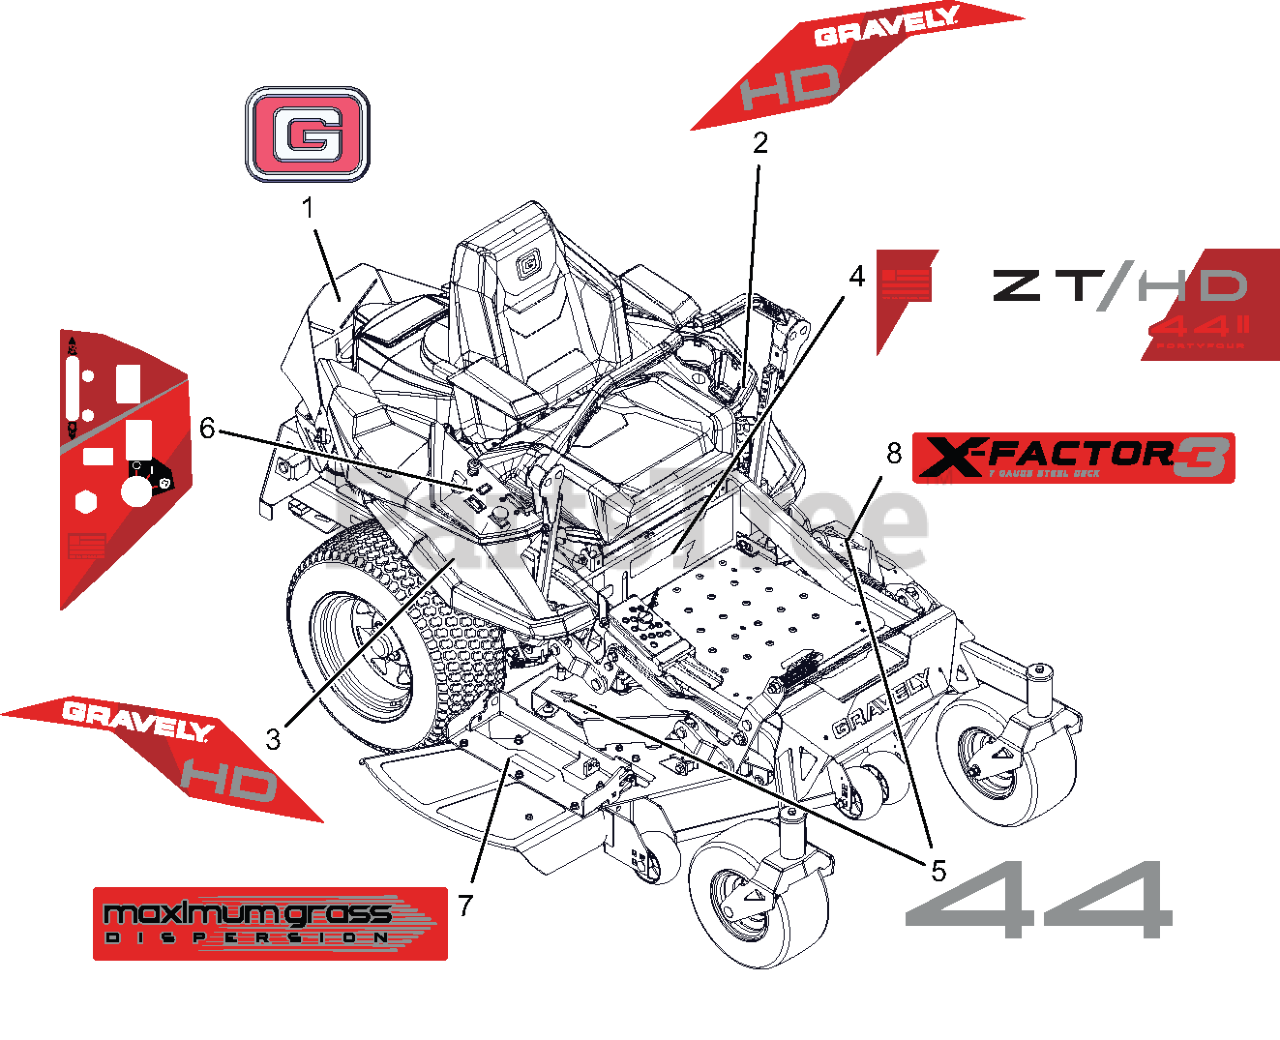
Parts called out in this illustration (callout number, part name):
1	DECAL, GRAVELY BRAND
2	DECAL, FENDER LH - HD
3	DECAL, FENDER RH - HD
4	DECAL, ZT/HD - 44
5	DECAL, DECK - 44
6	DECAL, CONTROL PANEL
7	DECAL, DECK - MAX GRASS
8	DECAL, DECK - X-FACTOR 3 7 GAUGE
